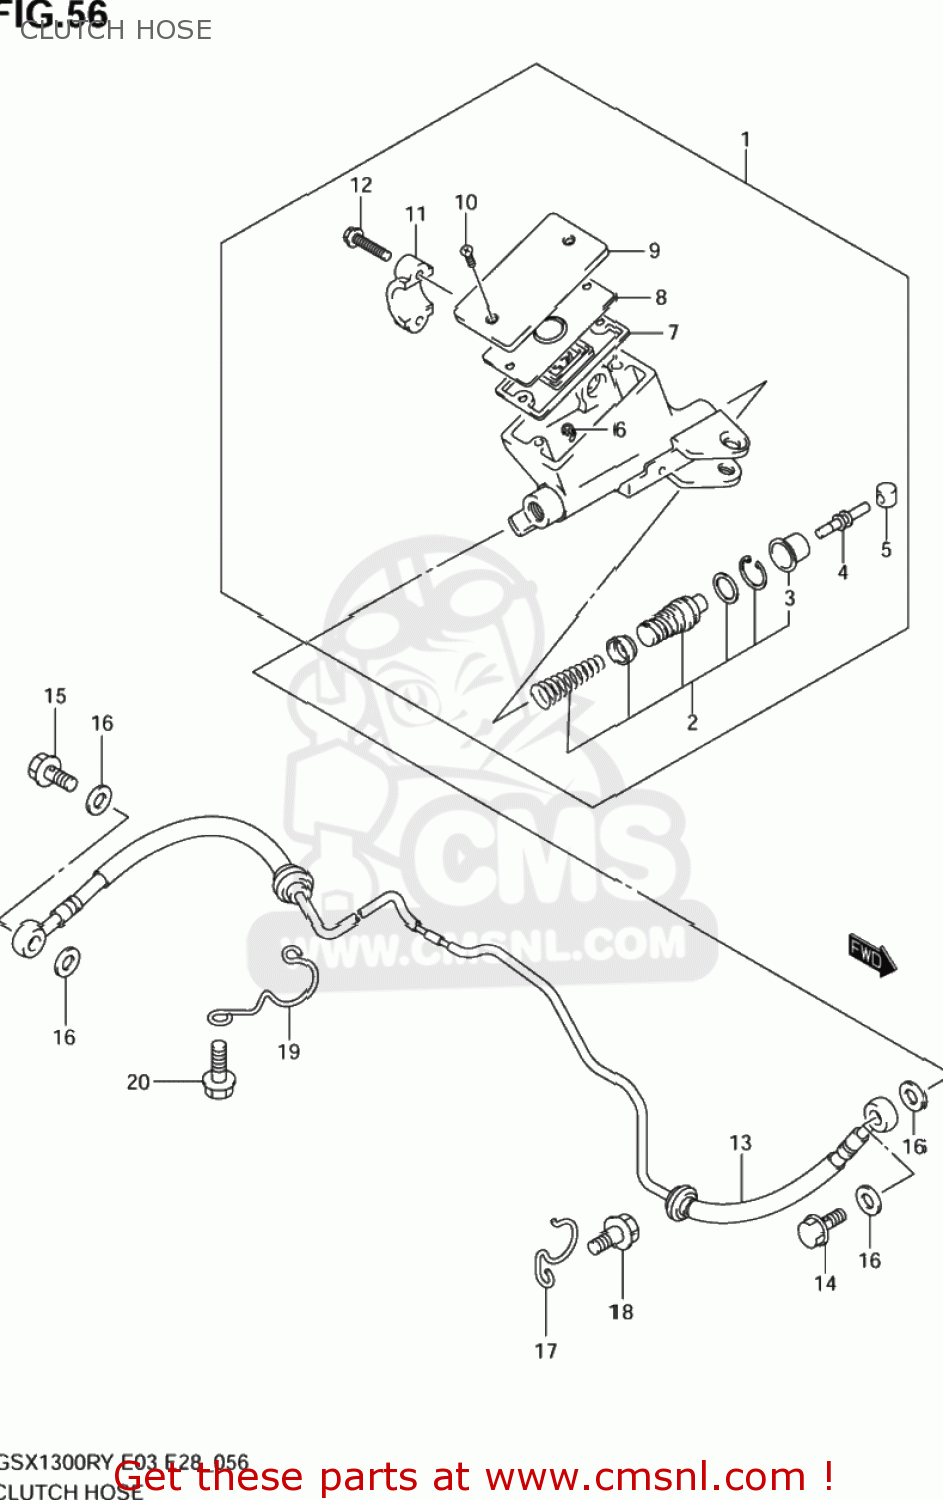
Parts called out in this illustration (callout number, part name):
1	CYLINDER ASSEMBLY,CLUTCH MASTER
2	PISTON & CUP SET
3	BOOT
4	PUSH ROD
5	BUSH
6	PROTECTOR
7	8
8	PLATE,DIAPHRAGM
9	CAP
10	SCREW
11	HOLDER
12	BOLT(6X22)
13	HOSE,CLUTCH
14	BOLT UNION
15	BOLT UNION
16	WASHER(10X15X1.5)
17	CLAMP,CLUTCH HOSE NO.1
18	BOLT
19	CLAMP,CLUTCH HOSE NO.2
20	BOLT
